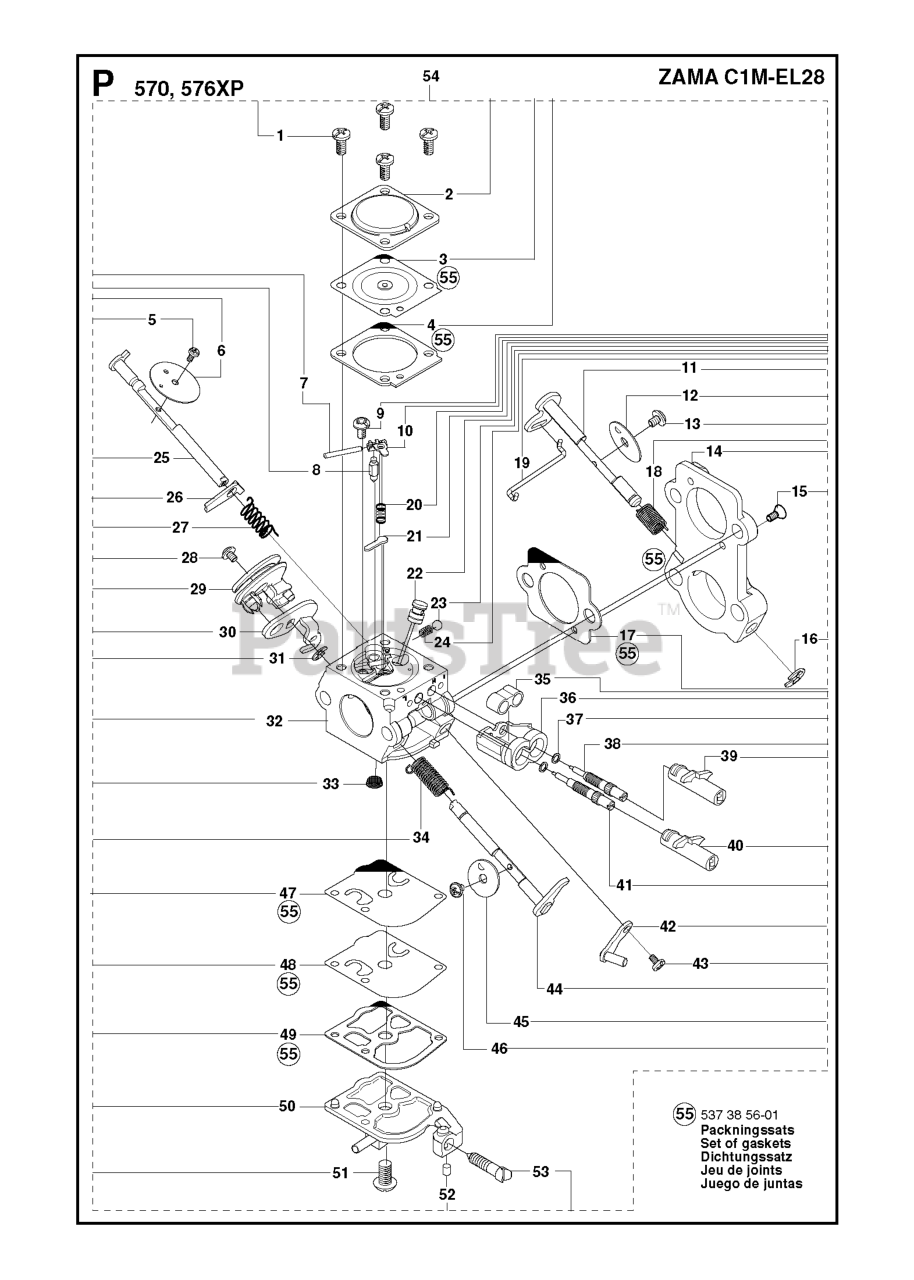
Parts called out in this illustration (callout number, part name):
6	CHOKE FLAP
7	PIN RETAINING SCREW
8	INLET NEEDLE
12	THROTTLE FLAP
14	RP CARBURETOR
25	CHOKE SHAFT
32	RP CARBURETOR
38	NEEDLE HIGH SPEED
41	LOW SPEED NEEDLE
44	THROTTLE SHAFT
47	PUMP DIAPHRAGM
54	RP CARBURETOR
55	GASKET SET
